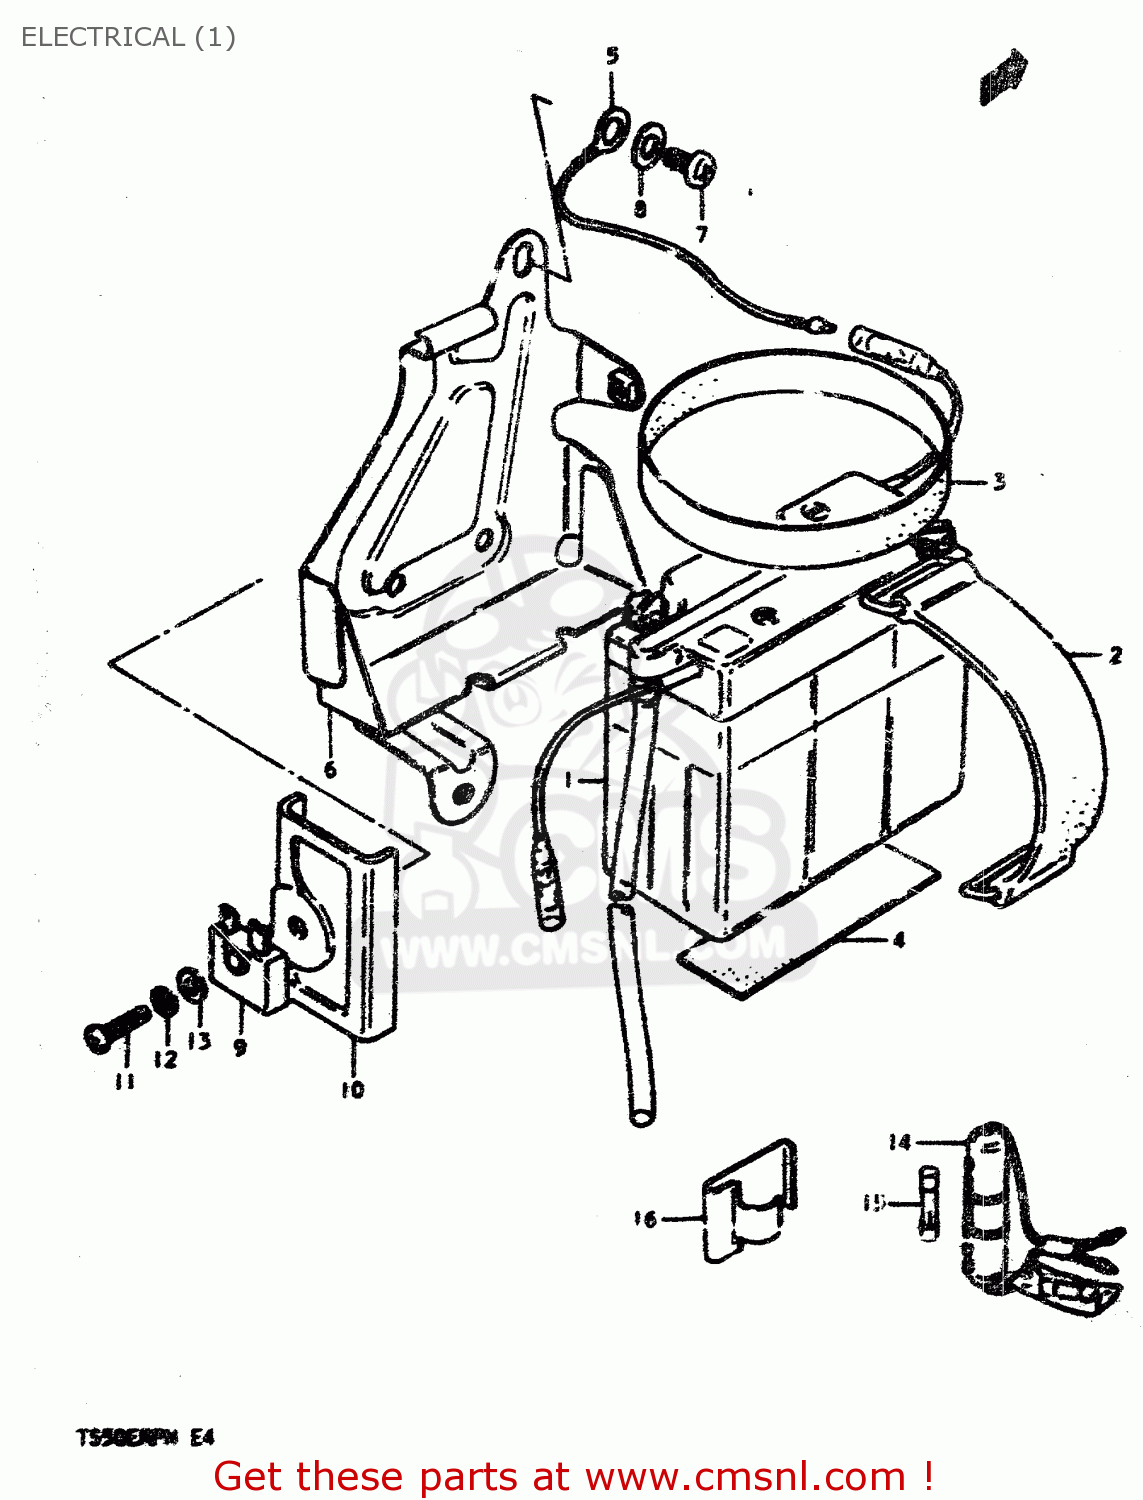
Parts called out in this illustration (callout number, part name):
1	BATTERY(6N4B-2A,6V4.2AH)
2	BAND
3	PROTECTOR,BATTERY
4	PROTECTOR(170X95X3.0)
5	LEAD WIRE
6	HOLDER, BATTERY
7	SCREW 6X12
8	WASHER
9	RECTIFIER ASSEMBLY
10	PROTECTOR
11	SCREW
12	LOCK WASHER
13	WASHER
14	BOX ASSEMBLY,FUSE
15	FUSE(10A)
16	HOLDER,FUSE CASE
